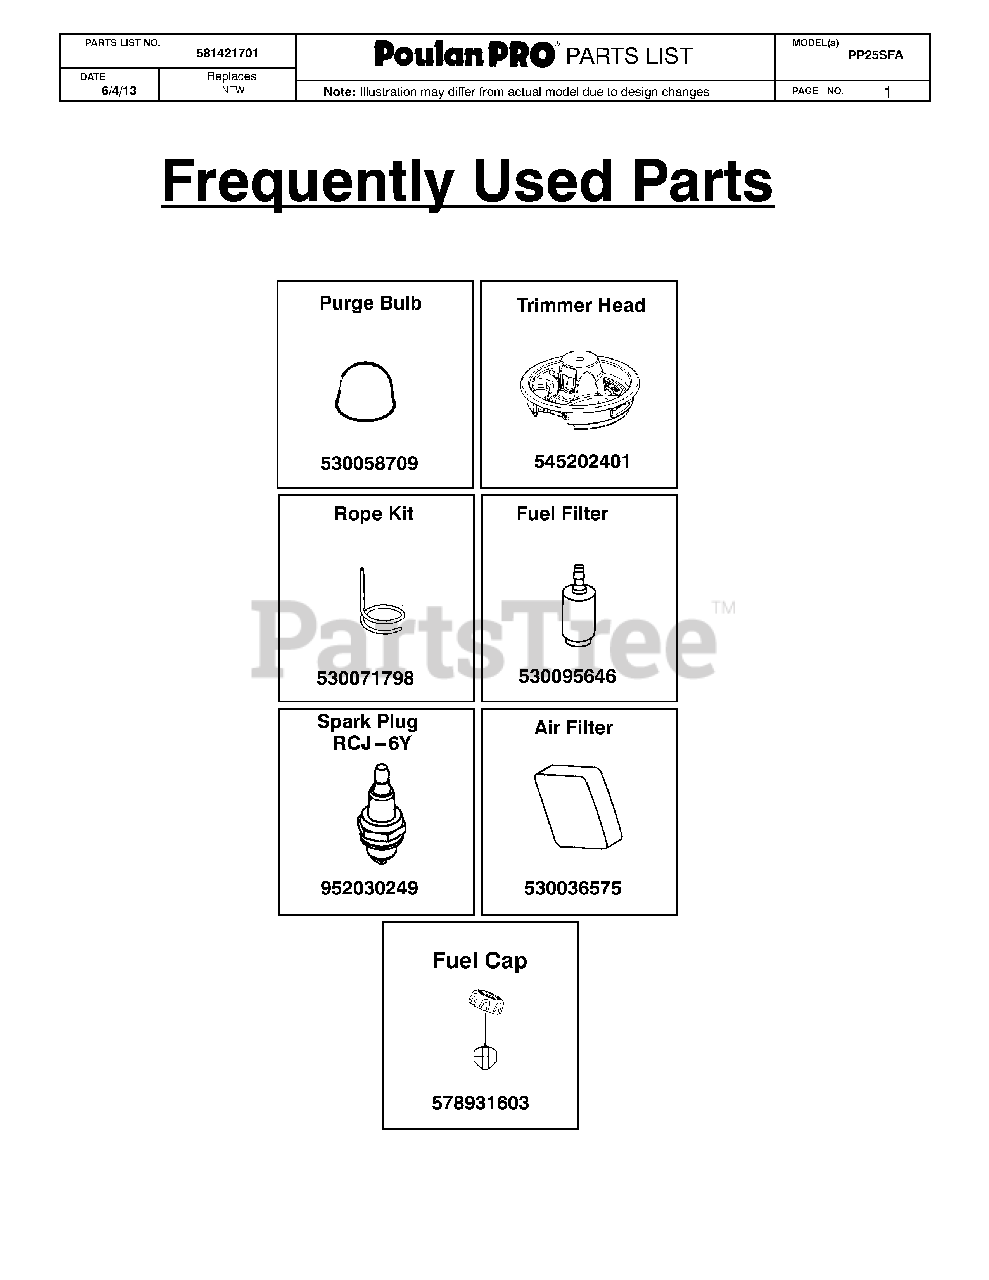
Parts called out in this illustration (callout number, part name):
1	PURGE BULB ZAMA
2	HEAD CUTTING FIXED LINE
3	KIT ROPE
4	FUEL PICK-UP ASSY
5	PLUG-SPARK (RCJ-6Y)
6	AIR FILTER
7	FUEL CAP ASSY
